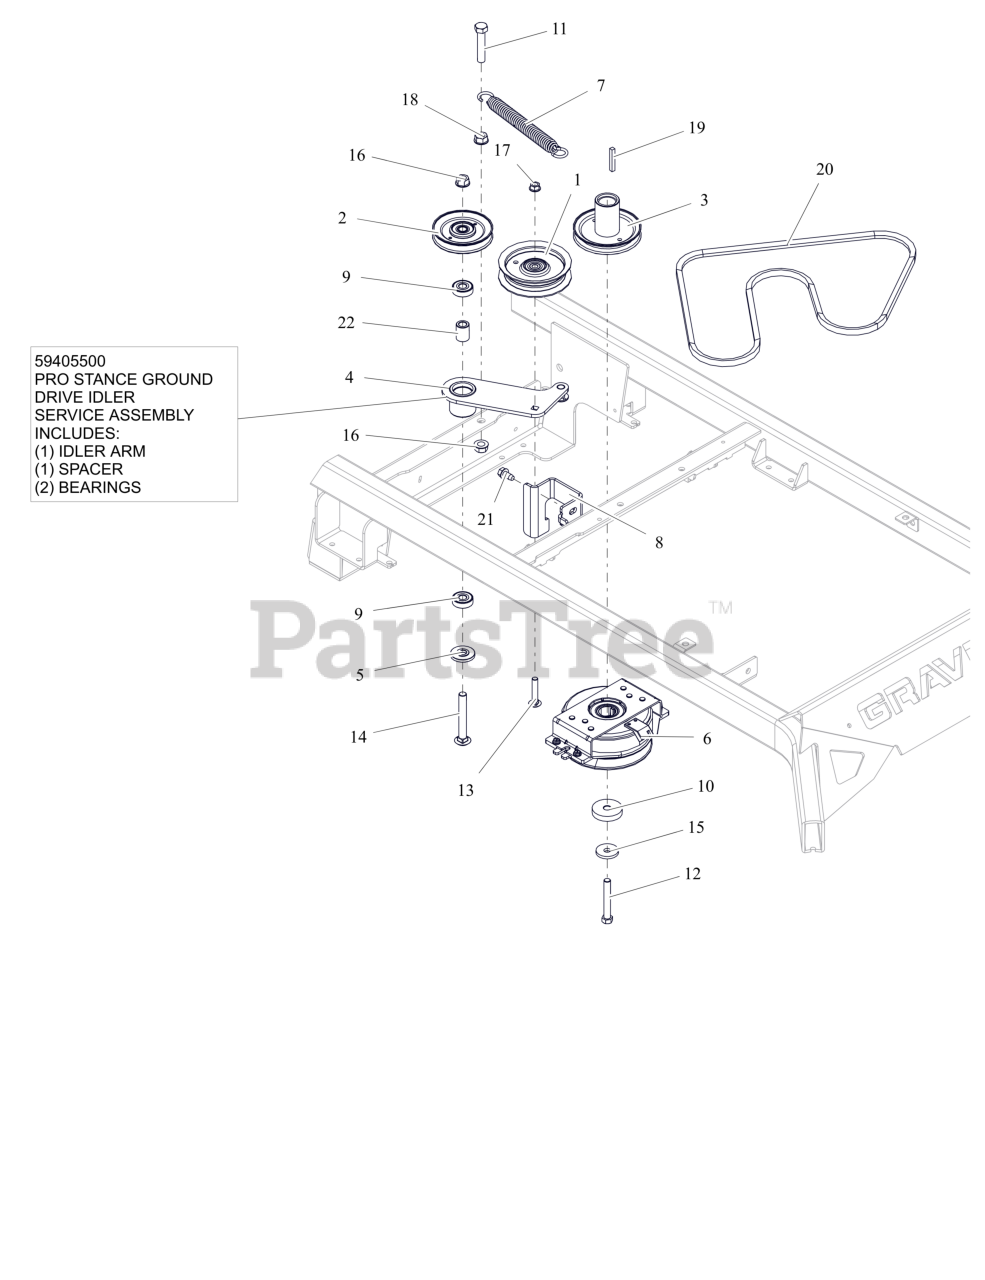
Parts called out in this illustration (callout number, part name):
1	IDLER, FLAT - 4.06" X .75"
2	SHV, .50"ID X 4.00"OD V-IDLER
3	SHEAVE- ENGINE 4.50 X 1.127 ID
4	WELDMT, IDLER ARM
4	GROUND DRIVE IDLER ASSEMBLY
5	SPACER, IDLER ARM
6	CLUTCH, OGURA GT2.75-BBO1
7	SPRING- EXTENSION
8	BRKT, CLUTCH STOP (BLACK)
9	BRG-BALL .500X1.38X.437
10	SPACER, .450X2.00X.396
11	BLT, HEX .50-13X2.50 G5 ZCC
12	BLT, HEX 0.4375-20X3 G8 ZCC NT
13	BLT, RHSN .38-16X2.00 G5 ZCC
14	BTL,RHSN .500-13 X 3.75 G5 ZCC
15	WASHER, 7/16" SPRING DISK
16	NUT-LK-CTR-FLG .500-13 GG ZCC
17	NUT-LK-CTR-FLG .375-16 GF ZCC
18	NUT, SPNLK-FLG .50-13 G5 ZCC
19	KEY-STR .25X1.75X.25
21	SCR,TAP .375-16X.75 HWH TR ZCC
22	SPACER .510 X .867 X 1.1485
